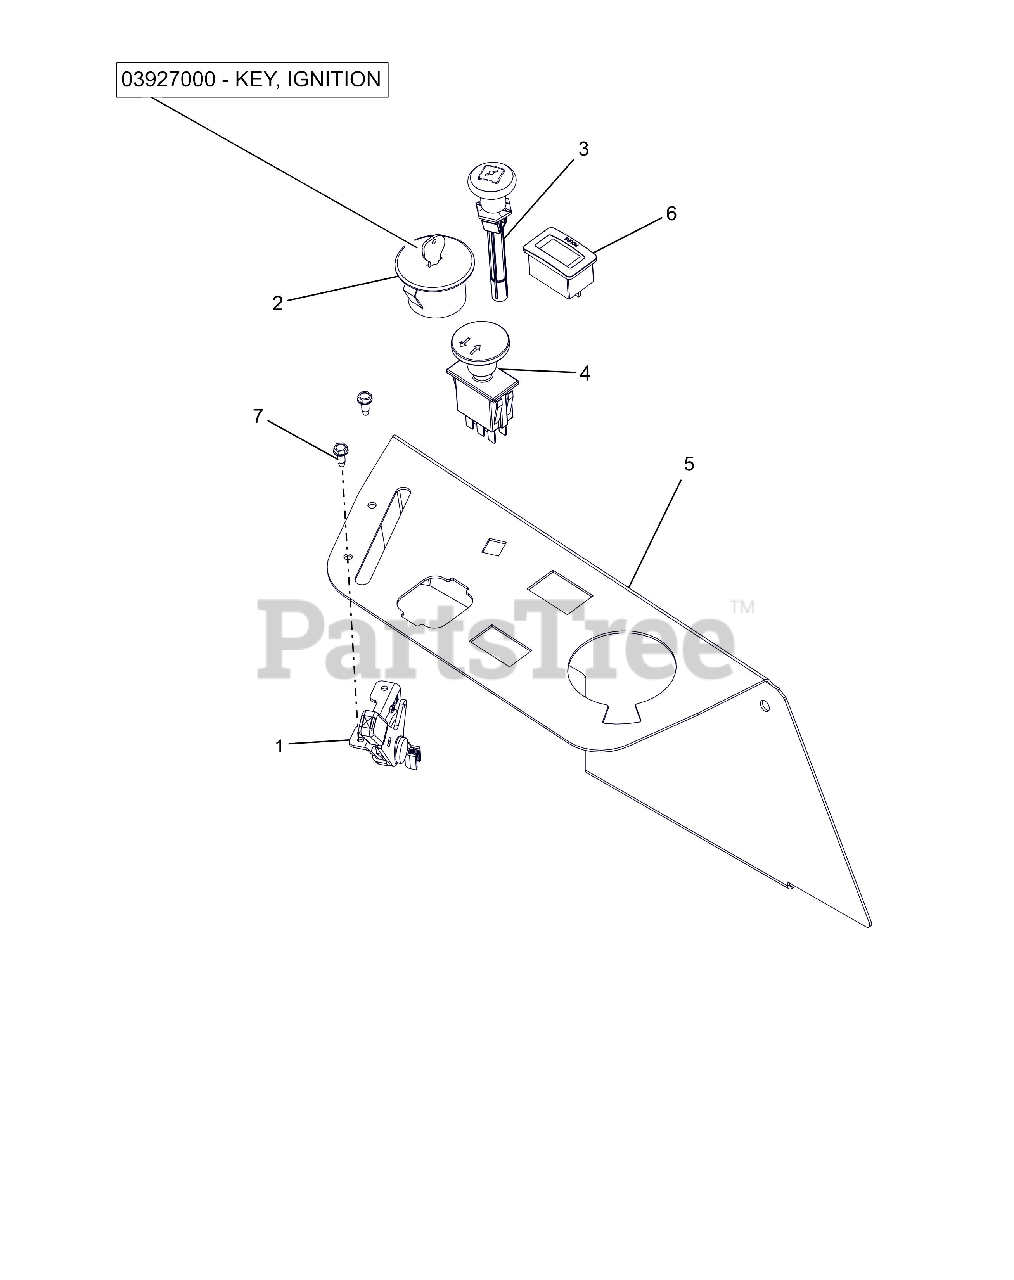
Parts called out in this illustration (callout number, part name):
1	CABLE - THROTTLE CONTROL
2	KEY, 03290500 KEYSWITCH
3	KEYSWITCH-IGNITION 4 POS
3	KEYSWITCH-IGNITION 3 POS
3	CABLE - CHOKE, SNAP-IN
4	SWITCH, CLUTCH (YELLOW)
5	PANEL, RIGHT SIDE FENDER MOUNT
6	HOUR METER
7	@SCR-TAP 10-24X.50 HWH TR YWZC
